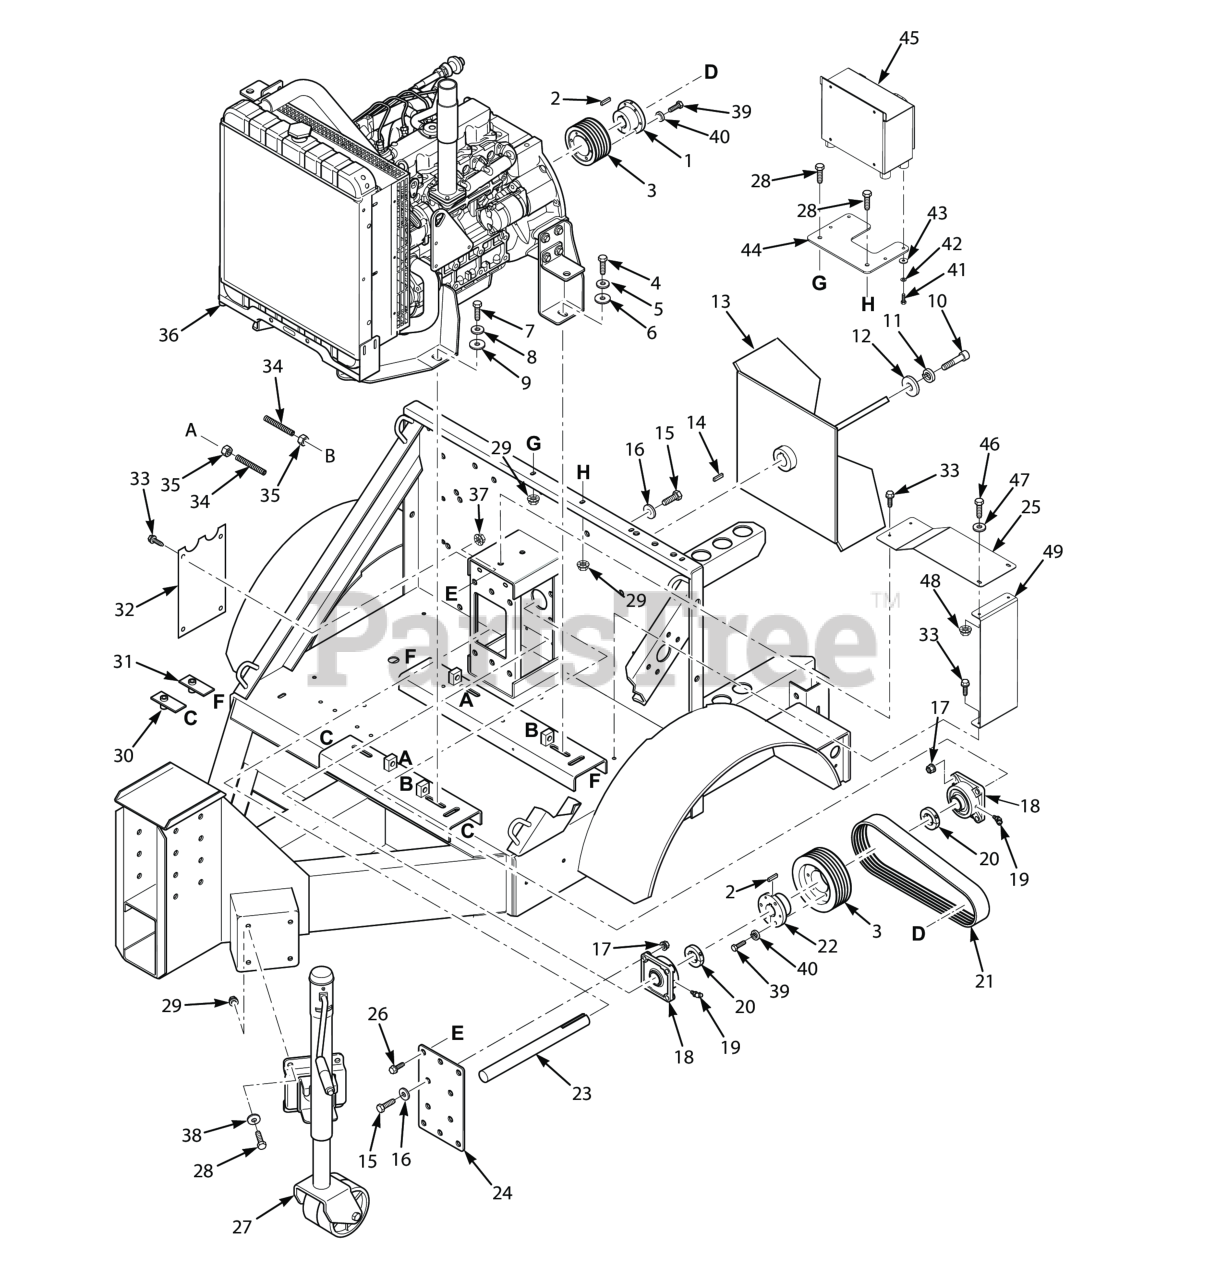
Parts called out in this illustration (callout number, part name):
1	Bushing, Tapered Lock SK 1-1/2"
2	Key, 3/8 x 3/8 x 2-1/4"
3	Pulley, Sheave 3V6.5 x 5 SK
4	Bolt, Hex Head, 5/8-11 x 1-3/4"
5	Lockwasher, 5/8" Spring
6	Flatwasher, 5/8-.688 x 1-3/4 x .134 HD
7	Bolt, Hex Head 1/2-13 x 1-3/4"
8	Lockwasher, 1/2" Spring
9	Washer, Flat, 1/2-.562 x 1.375 x .109 HD
10	SHCS, 5/8-18 x 2-1/2"
11	Lockwasher, 5/8" Spring
12	Flatwasher, 5/8-.688 x 1-3/4 x .134 HD
13	Impeller, STL 4 Blade - 24-3/4" OD
14	Key, 3/8 x 3/8 x 4-1/2"
15	Bolt, Hex Head 1/2-13 x 1-3/4"
16	Flat Washer, 1/2 (.562 x 1.375 x .109)
17	HEX LOCKNUT, ELASTIC STOP, 1/2-13
18	Bearing, Flange Mount
19	Grease Fitting
20	Collar. 2 pc 1-7/16
21	Belt, R3V x 425-5
22	Bushing, Taper - SK 1-7/16" (incl. hardware)
23	Shaft, Impeller
24	Bearing Mount Plate
25	Shield, Top
26	Capscrew, 1/2-13 x 1" Serrated Flange Hex Head
27	Jack, Trailer 2-Wheel
28	Bolt, Hex Head, 3/8-16 x 1 Gr. 5
29	NUT, 3/8-16 SERRATED FLANGE HEX HEAD
30	Nut Plate Weldment, 1/2-13
31	Nut Plate Weldment, 5/8-11
32	Belt Cover, RH Diesel
33	Screw, Hex Head 5/16-18 x 3/4" Self Tap
34	SET SCREW, 1/2-13 X 4 HEX SOCK
35	NUT, HEX #10-32
36	Engine, Kubota 49hp Diesel (not avail. thru Scag)
37	Nut, Hex Serrated Flange 1/2-13
38	Flatwasher, 3/8" Special (.391 x .938 x .105)
39	CAPSCREW, HEXHEAD 7/16-14 X 1.50
40	Lockwasher, 5/16 (.317 x .586 x .078) Helical Spring
41	BOLT, HEX HEAD, 1/4-20 X 3/4 GR.5
42	Lockwasher, 1/4� Spring
43	Flatwasher, 1/4" (.312 x .750 x .065")
44	Mounting Bracket, Control Box
45	Control Panel
46	Bolt, Heax Head 5/16-18 x 1" (48V / 52V)
47	Flatwasher, 5/16-.375 x .875 x .083 (35BV & 37BV-EFI)
48	Nut, Flange Head Elastic Stop 5/16-18
49	Shield, Side
